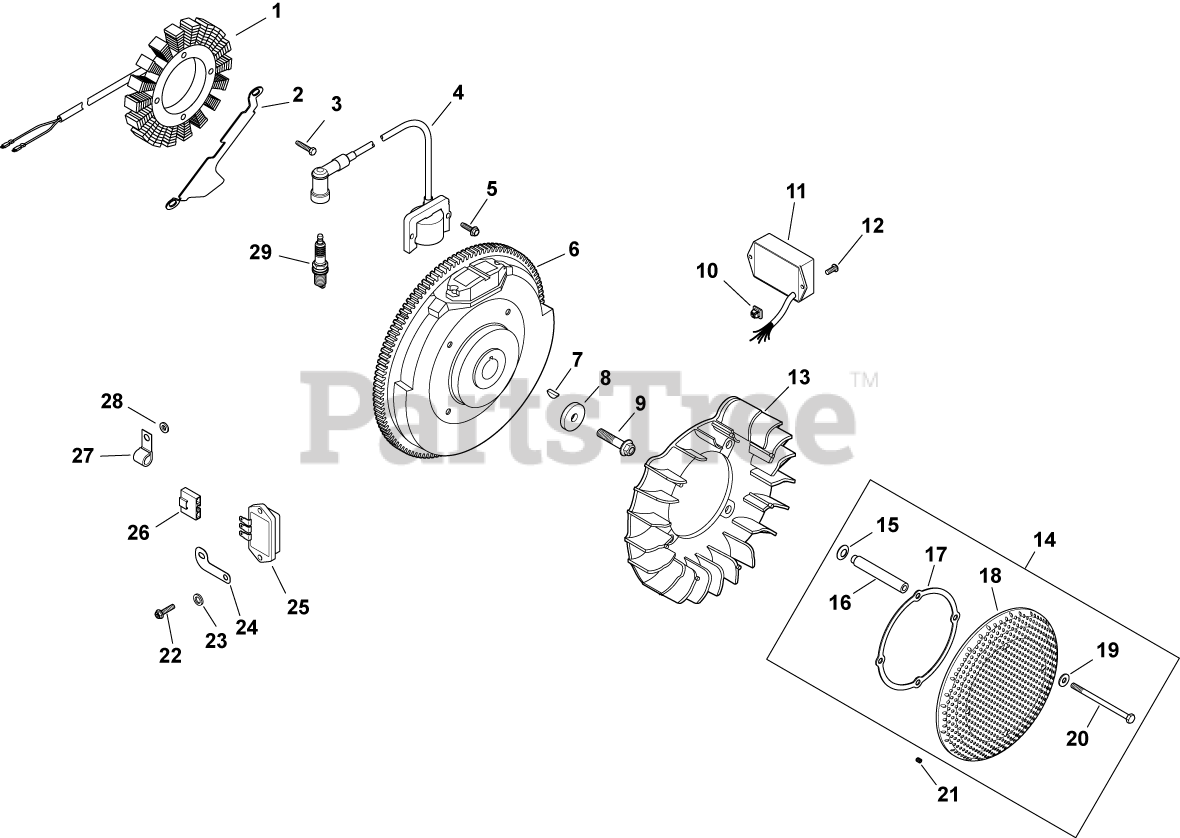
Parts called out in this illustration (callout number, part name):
1	KIT, 15 / 20 AMP STATOR
2	BRACKET, STATOR WIRE
3	SCREW, M5X0.8X25 - (#25086402S)
4	MODULE, IGNITION
5	SCREW, FLG THD FRM M5X.8X20-(#25086399S)
6	FLYWHEEL ASSEMBLY (LW)
7	KEY, 3/16" X 5/8"
8	WASHER, FLAT 13/32"
9	SCREW, FLG M10X1.5X45 - (#25086361S)
10	NUT, PLASTIC
11	MODULE, SPEED ADVANCE
12	SCREW, PHL HD #11-16X1/2"
13	FAN USE 24 157 11-S
14	KIT, CHOPPER SCREEN
15	WASHER, SPRING 10 MM
17	RING, SUPPORT USE 25 141 08-S
18	SCREEN, GRASS
19	WASHER, FLAT 1/4" (O.D. 5/8")
20	SCREW, SOCKET TRUSS HD CAP
21	SCREW, SKT SET #10-24X1/4"
22	SCREW, PHL HD #11-16X7/8"
23	WASHER, FLAT 3/16"
24	BRACKET, GROUND STRAP USE 24 518 12-S
25	REG/RECT-15 AMP (KM)-USE 41 403 10-S
26	CONNECTOR
27	CLIP, CABLE
28	WASHER, FLAT 1/4" (O.D. 1/2")
29	PLUG, SPARK (STD)
